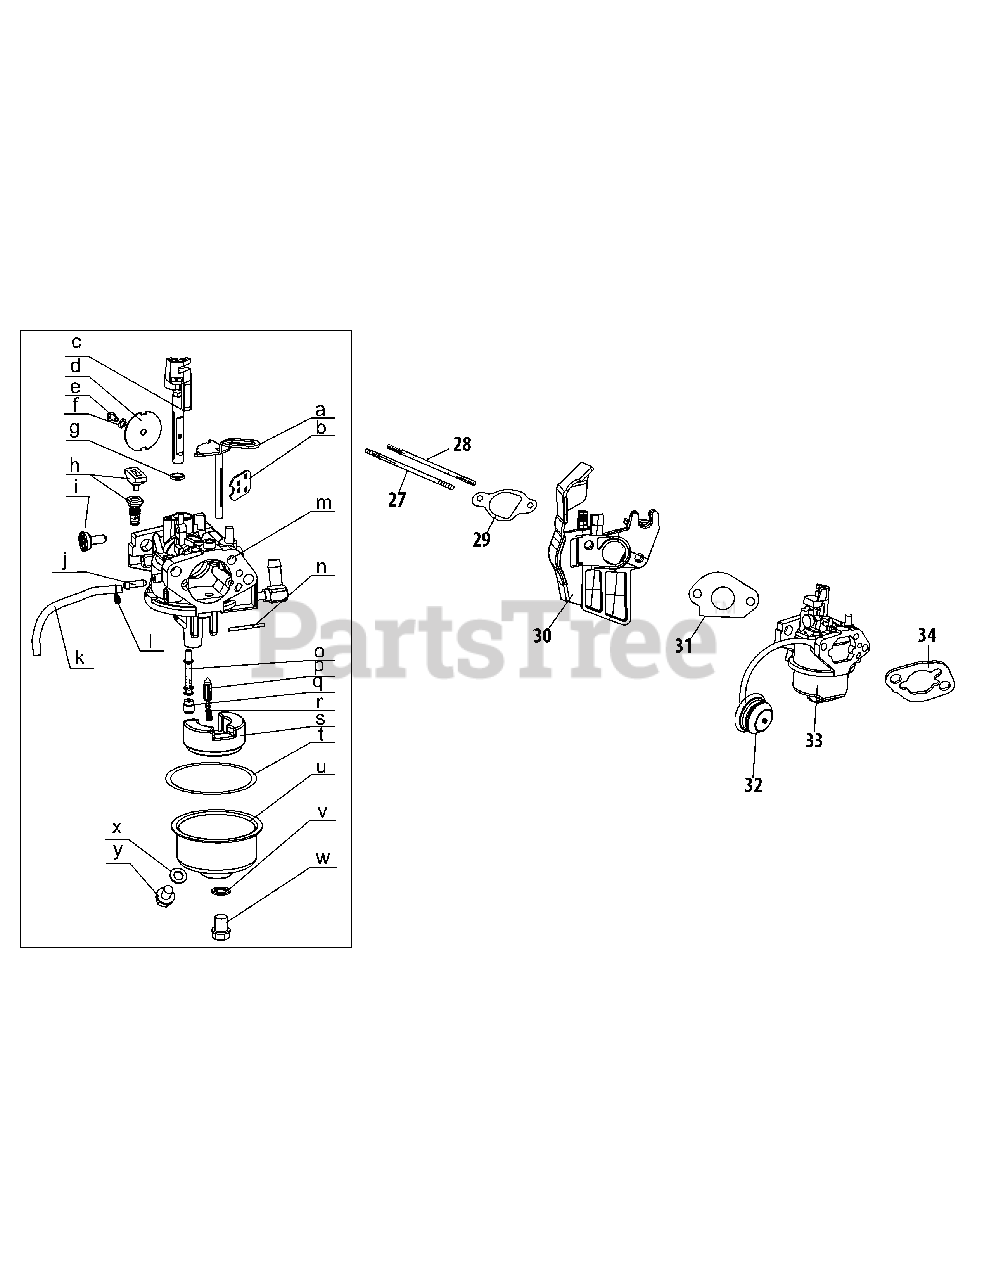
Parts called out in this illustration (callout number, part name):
27	Stud M6×117
28	Stud M6×105
29	Carburetor Insulator Gasket
30	Carburetor Insulator
31	Carburetor Gasket
32	Primer Assembly
32	Primer Bulb
33	Carburetor Assembly
34	Carburetor Gasket Plate
